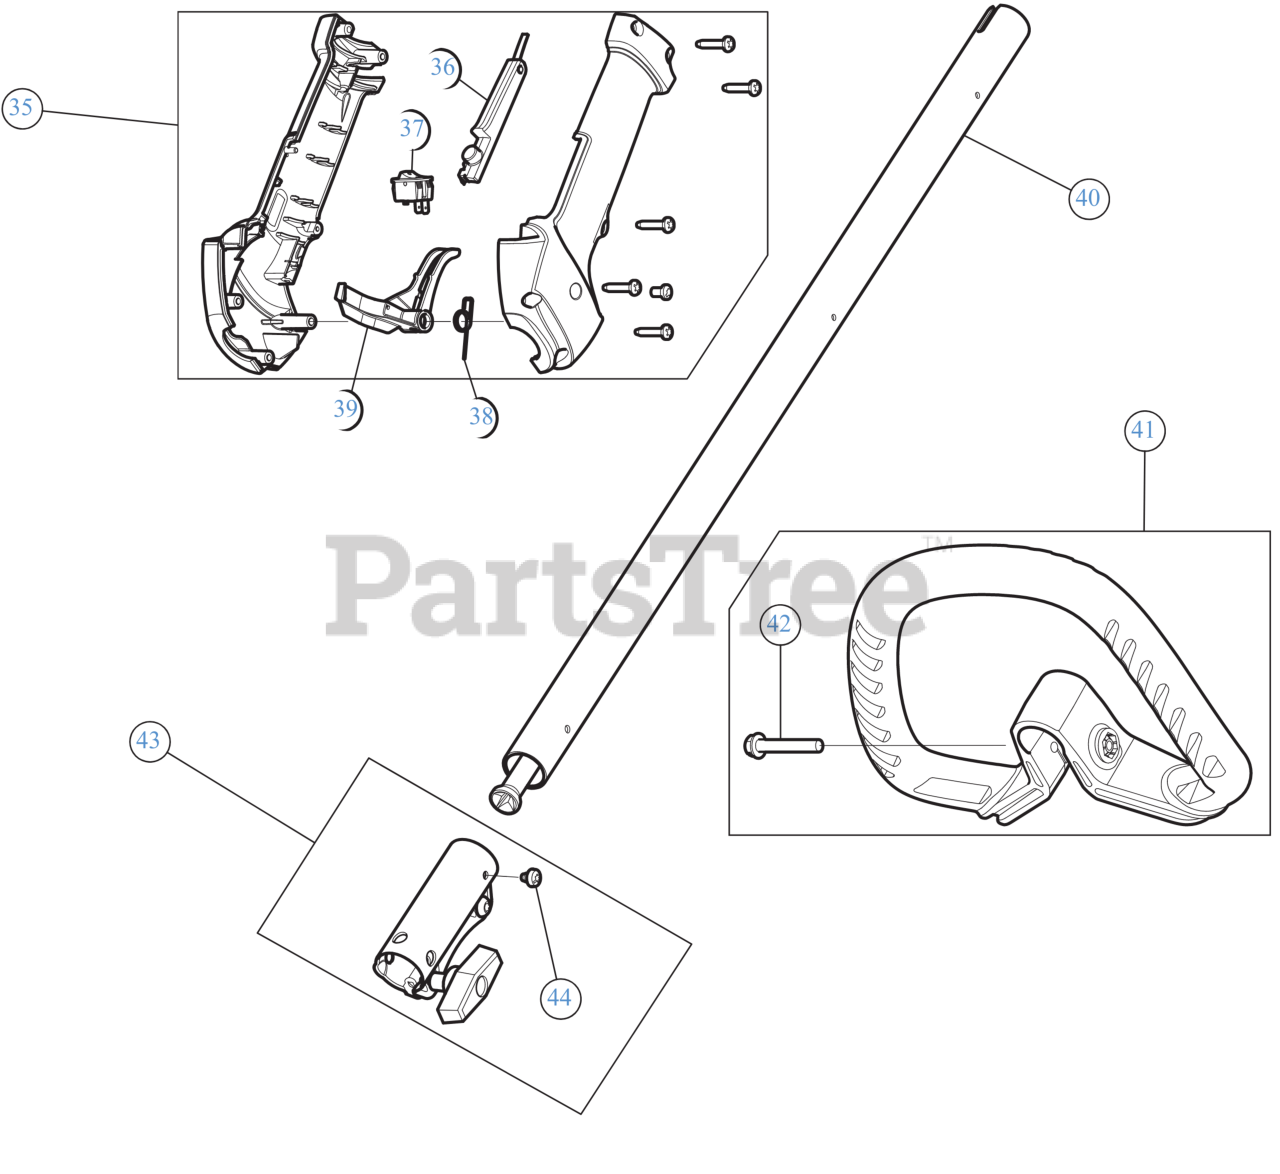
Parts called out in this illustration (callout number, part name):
35	THROTTLE GRIP ASSEMBLY
36	LEVER LOCK OUT
37	SW, MOMENTARY ON/O
38	SPRING TRIG
39	THROTTLE TRIGGER
40	BOOM ASSEMBLY UPR
41	D-HANDLE
42	BOLT 1/4-20X1 1/2
43	SPLIT BOOM COUPLER KIT
44	SCREW, 10-32X.250 TA
